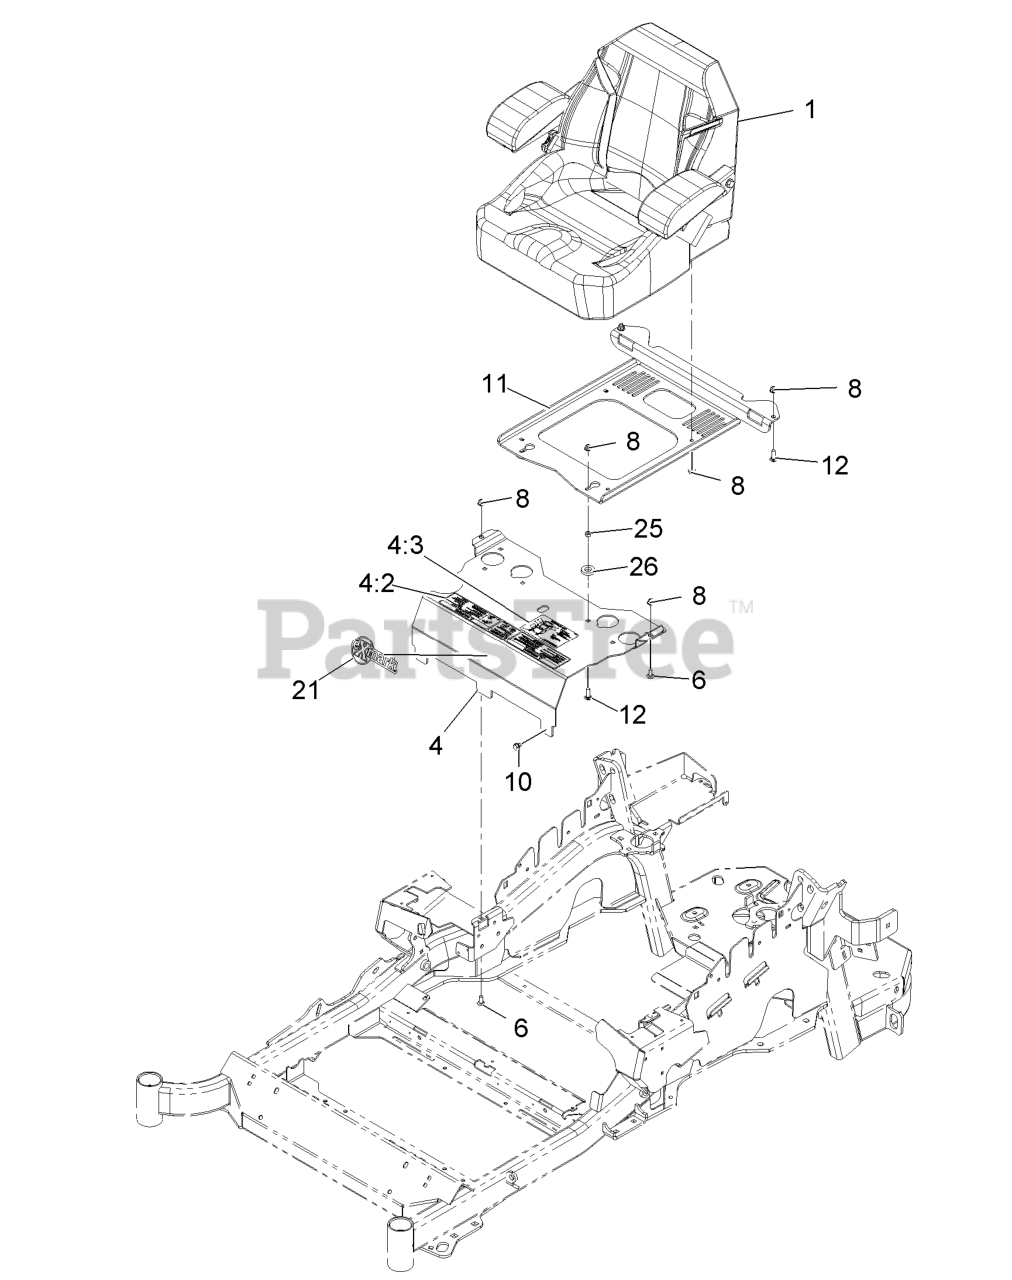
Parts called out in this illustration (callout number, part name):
4	MOUNT-SEAT
4:2	DECAL-CONSOLE
4:3	DECAL-SERVICE AID
6	SCREW-CARR
8	NUT-HF, NI
11	PLATE-SUPPORT, SEAT
12	SCREW-CARR
25	NUT-HEX
